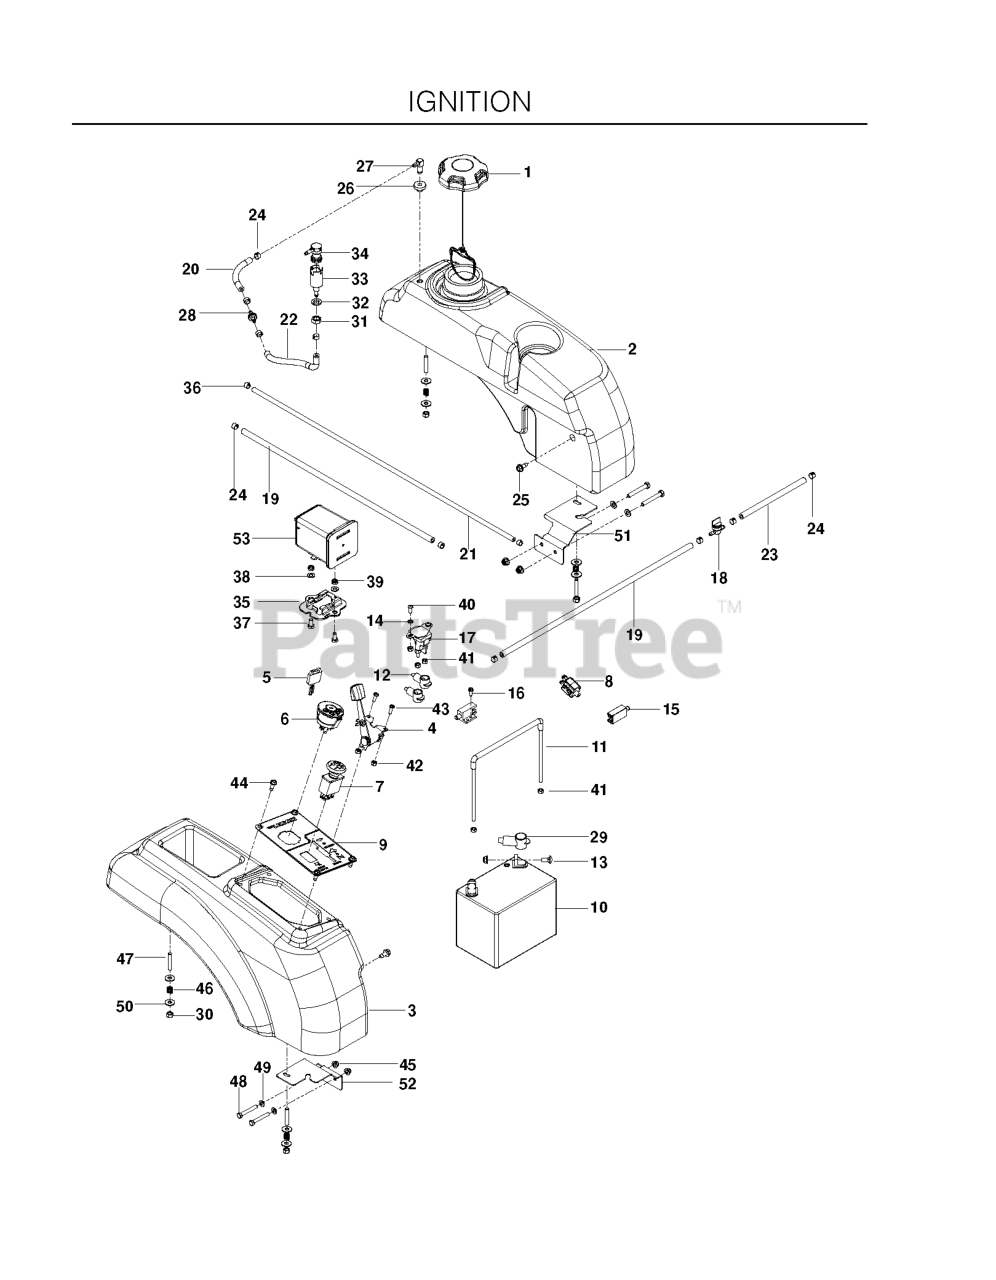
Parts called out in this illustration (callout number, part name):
1	CAP, FUEL
2	FUEL TANK ASSY, LT
3	FENDER RH
4	THROTTLE CABLE
5	KEY
6	IGNITION SWITCH
7	SWITCH, BLADE
8	SWITCH, BRAKE 3P
9	DECAL, CONTROL PANEL
10	BATTERY, 12 V 330 AMP TBR
11	BATTERY TIE DOWN ASSEMBLY
12	TERMINAL COVER-SM
13	BOLT 5/16C X 3/4" CARRIAGE
14	WASHER 1/4 INT TOOTH
15	SWITCH, INTERLOCK
16	SCREW #10 X 1/2 SELF TAPPING
17	SOLENOID
18	FUEL VALVE
19	FUEL LINE 24"
20	FUEL LINE 5"
21	FUEL LINE 33"
23	HOSE 1/4 X 8
24	HOSE CLAMP
25	BOLT 5/16-18 X 3/4
26	RUBBER GROMMET
28	VALVE, ANTI-SLOSH
29	INSULATOR
30	NUT 5/16 NYLOC
31	NUT 1/2 HEX JAM
32	WASHER 1/2" SPLIT LOCK
33	BODY, ROLLOVER VALVE
34	VALVE.SLANT.CARTRDG.90 DEG.TEX
35	BRACKET, CANISTER
36	CLAMP, HOSE
37	HCS 5/16-18 X 5/8 GR 5 ZD
38	FLAT WASHER 5/16 SAE
39	5/16-18 THIN PROF NY
40	SCR 1/4-20 X 5/8 BTN SKT HD ZD
41	NUT 1/4-20 NYLOC
42	NUT 10-24 NYLOC
43	SCREW #10-24 X 5/8
44	SCREW 1/4 X 5/8
45	5/16-18 NYLOC FLANGE NUT
47	STUD, 5/16C
48	CAPSCREW
49	FLAT WASHER 5/16 SAE
50	WASHER 5/16 FLAT
51	SUPPORT, TANK LT BLK
52	SUPPORT, TANK, RT BLK
53	CANNISTER, CARBON
